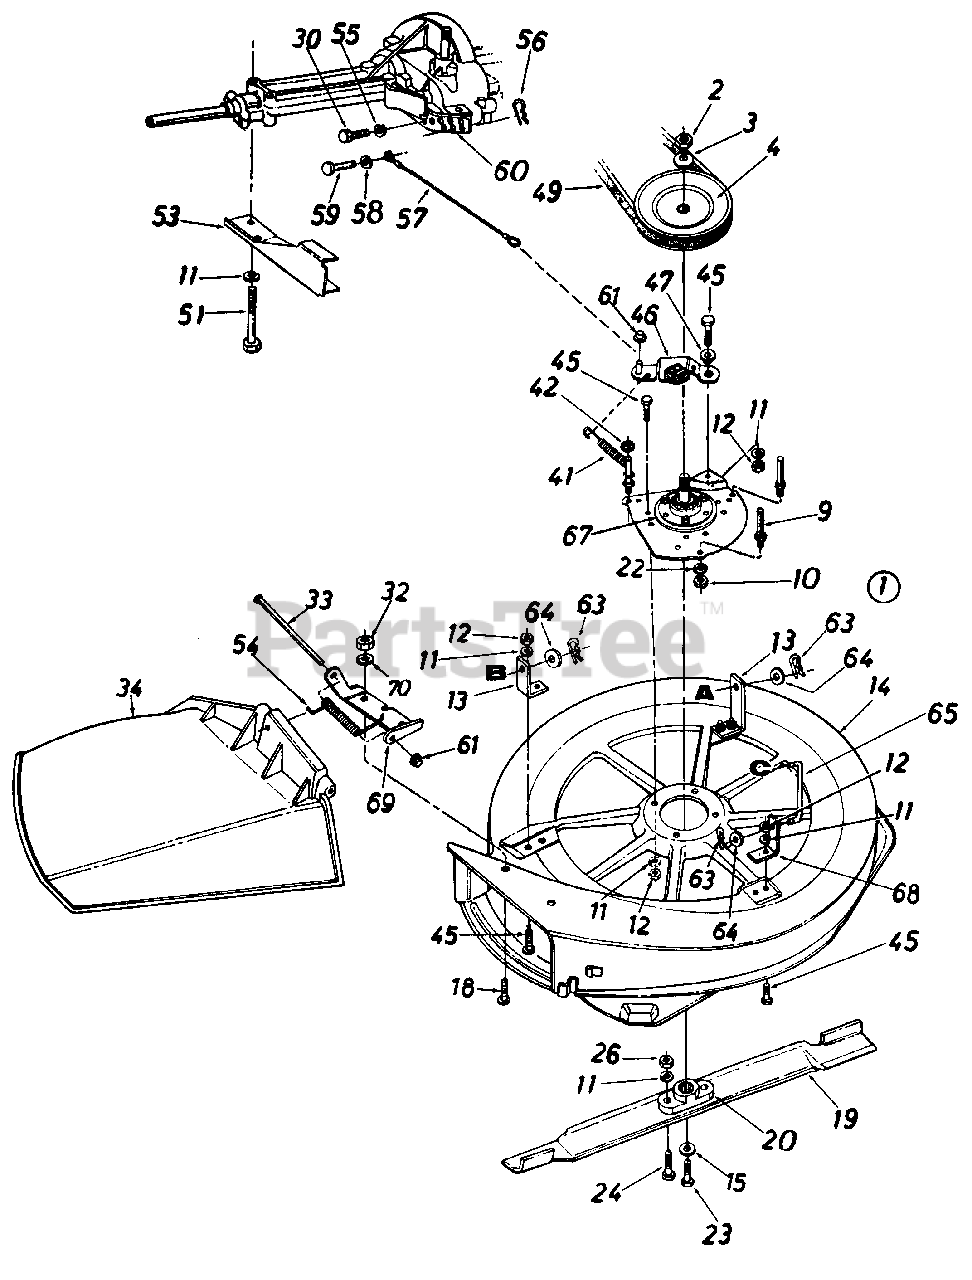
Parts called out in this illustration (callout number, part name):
1	30" S.D. Deck Ass'y. Comp.
2	Hex Jam Nut 5/8-18 Thd.
3	Bell-Wash. .630" I.D. x 1.25"
4	5/8 V-Pulley .75" I.D. x .7"
9	Stud 3/8-16 x 2.75" Lg.
10	Hex Jam Nut 3/8-16 Thd.
11	L-Wash. 5/16" I.D.
12	Hex Nut 5/16-18 Thd.
18	Truss Mach. Scr. 1/4-20 x .75" Lg.
19	30" High Lift Blade
20	Blade Adapter
22	L-Wash. 3/8" I.D.
23	Hex Bolt 3/8-24 x 1.0
24	Hex Bolt 5/16-24 x 1.0" Lg.
26	Hex Nut 5/16-24 Thd.
30	Hex Bolt 1/4-20 x .Son Lg.
32	Hex Nut 1/4-20 Thd.
33	Hinge Pin
34	Chute Ass'y. Comp.
41	Extension Spring
42	Push Speed Nut
45	Hex Bolt 5/16-18 x 75
46	Blade Brake Brkt. Ass'y.
47	Shoulder Spacer .500" Dia.
49	"V"-Belt
51	Hex Bolt 5/16-18 x 2.75"
55	L-Wash. 1/4" I.D.
56	Int. Cot. Pin 5/16" Dia.
57	Brake Cable 9.75" Lg.
58	Fl-Wash. .281" I.D. x .50"
59	Clevis Pin 1/4" Dia.
60	Lower Inside Belt Guard
61	Cap Speed Nut 1/4" Rod
63	Int. Cotter Pin 1/2" Dia.
64	Fl-Wash. .531" I.D. x .930"
65	Deck Link 3.9" Lg.
67	Blade Spindle Ass'y. Comp.
68	Weld Bracket
69	Hinge Mtg. Brkt.
70	Bell-Wash. 1/4" I.D.
